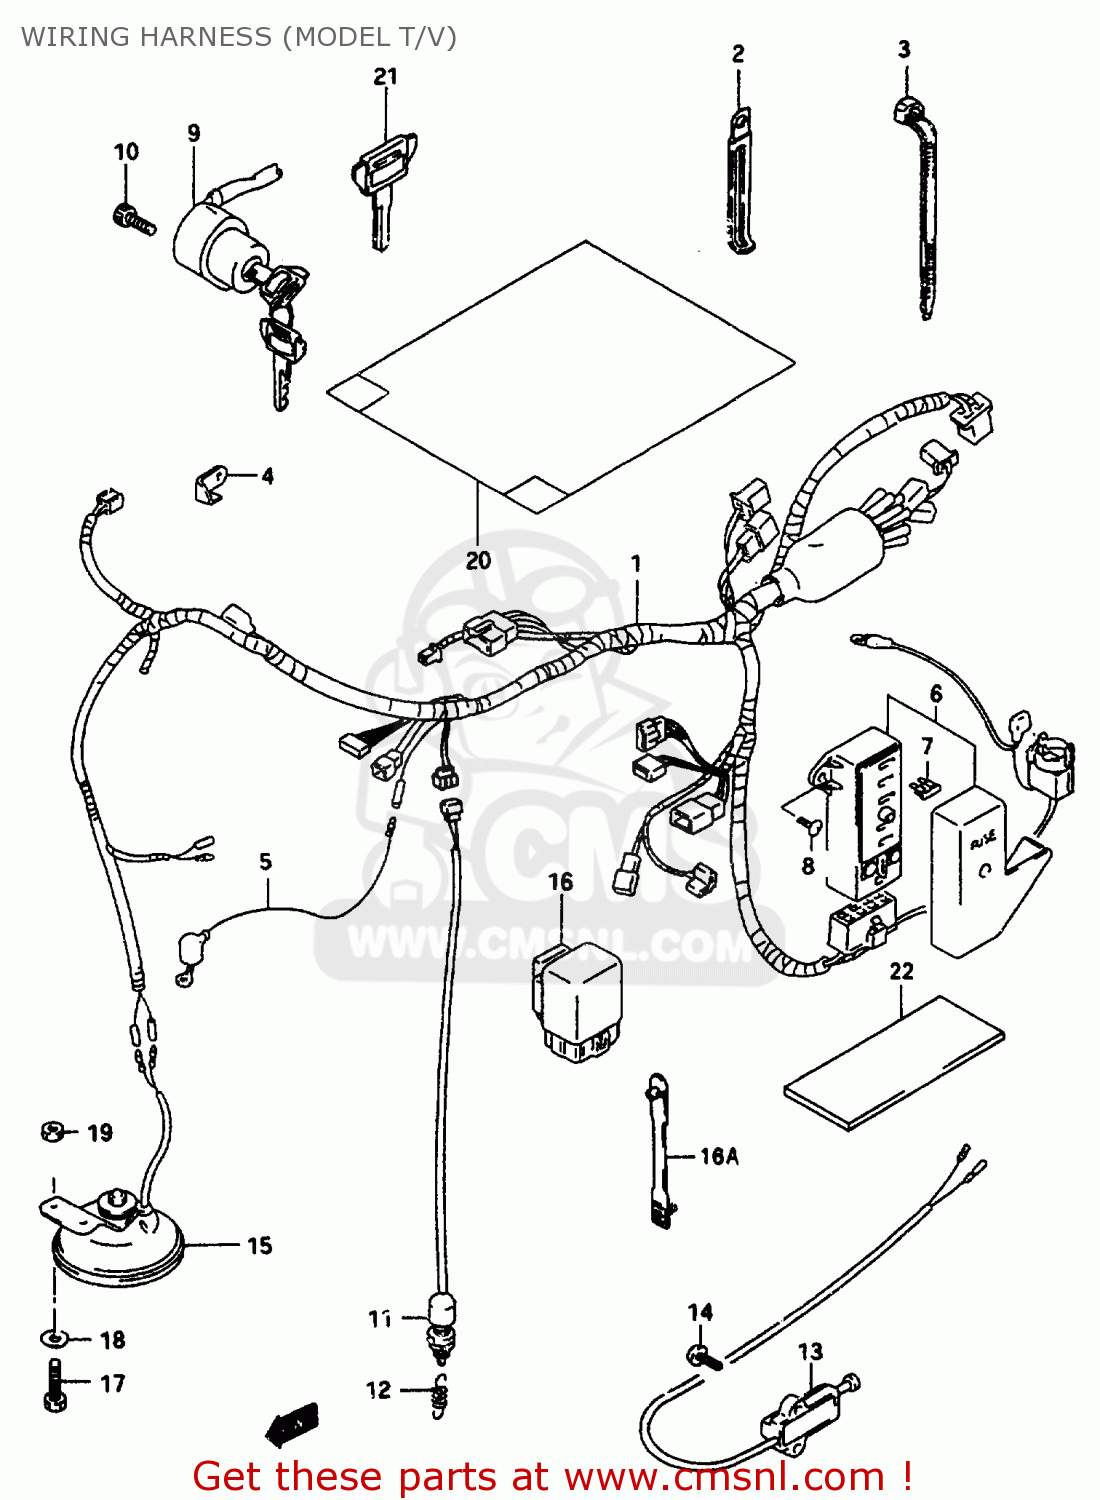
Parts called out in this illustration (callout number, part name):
1	HARNESS,WIRING
2	CLAMP(L:45)
3	CLAMP(L:95)
4	PLATE,COUPLER HOLDER
5	WIRE,WATER TEMP GAUGE LEAD
6	BOX ASSY,FUSE
7	FUSE(10A)
8	SCREW
9	SWITCH ASSEMBLY,IGNITION
10	BOLT
11	SWITCH ASSY,STOP LAMP
12	SPRING
13	SWITCH ASSY,SIDE STAND
14	SCREW
15	HORN ASSY
16	RELAY ASSY
16A	CLAMP,L:88
17	BOLT
18	WASHER
19	NUT 6MM
20	COVER,WIRING HARNESS
21	KEY,BLANK(TYPE:C)
22	COVER,HARNESS
